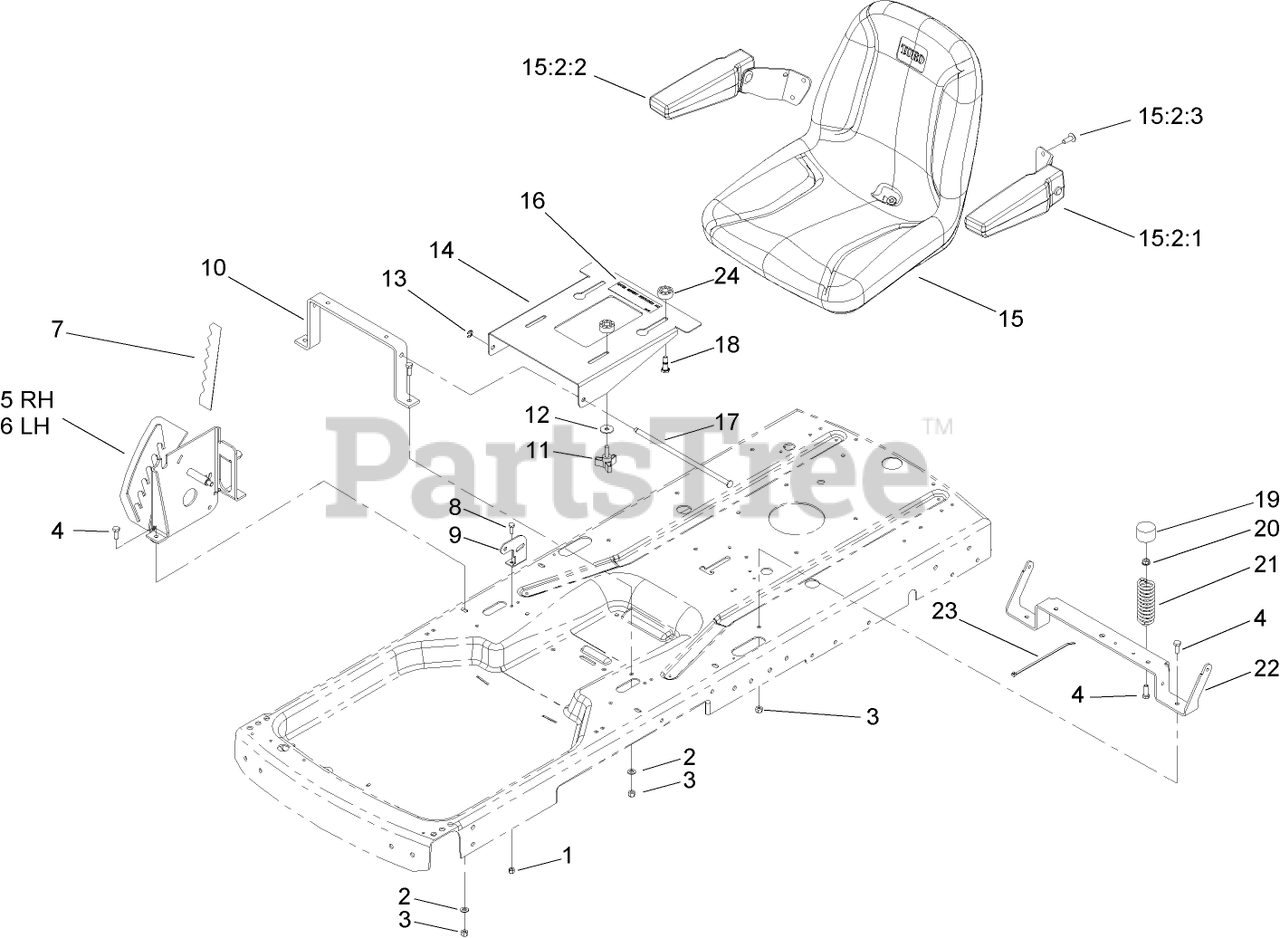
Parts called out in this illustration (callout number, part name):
1	NUT-LOCK, NI
2	WASHER-PLAIN
3	NUT-LOCK, NI
4	SCREW-HH
5	RH PLATE ASM
6	LH PLATE ASM
7	DECAL-HOC
8	SCREW-HH
9	BRACKET-BELLCRANK
10	BRACE-SEAT, FRONT
12	WASHER-PIVOT
13	E-RING
14	BRACKET-SEAT
15	SEAT (WITH ARM RESTS)
15:2	Loose Parts Package
15:2:3	SCREW-HSBH
16	DECAL-SERVICES
17	PIN-PIVOT
18	SCREW-SHOULDER
19	CAP-PROTECTOR
20	NUT-HF
21	SPRING-COMPRESSION
22	BRACE-SEAT, REAR
23	TIE-CABLE
24	SPACER-NYLON
